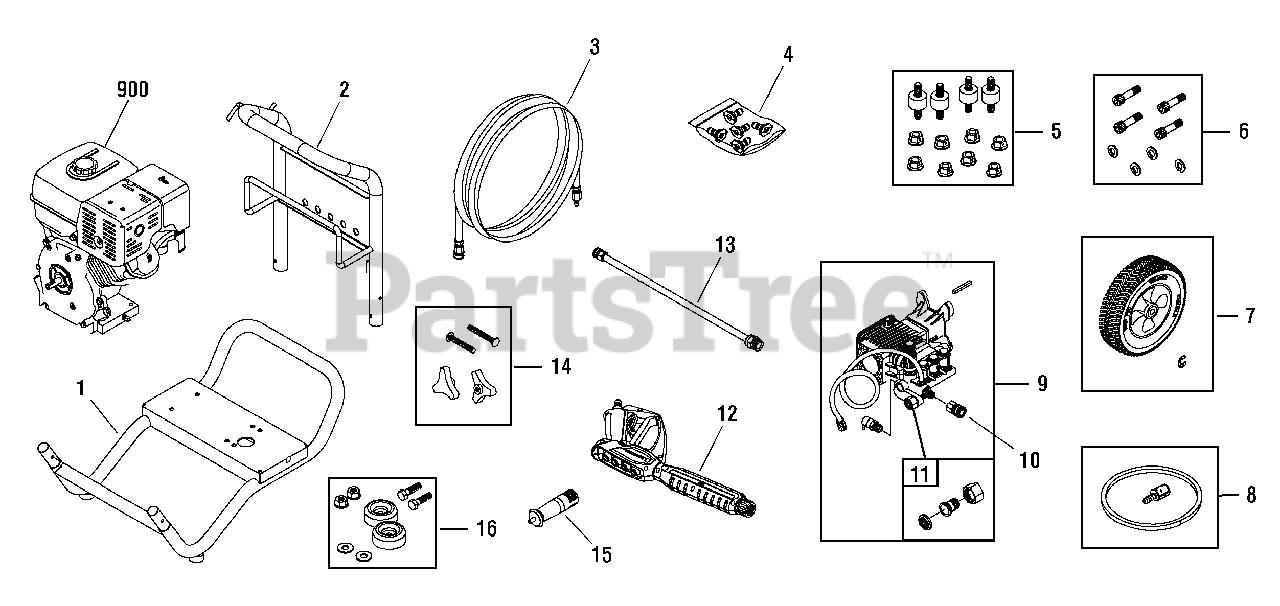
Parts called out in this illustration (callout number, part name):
2	HANDLE
4	KIT, QC Nozzle
5	KIT, Hardware, Engine Mounting
6	KIT, Hardware, Pump Mounting
9	PUMP
10	FITTING
11	ADAPTER, Garden Hose
13	EXTENSION, QC
14	KIT, HARDWARE, Handle
16	MOUNT, Vibration
900	* ENGINE
